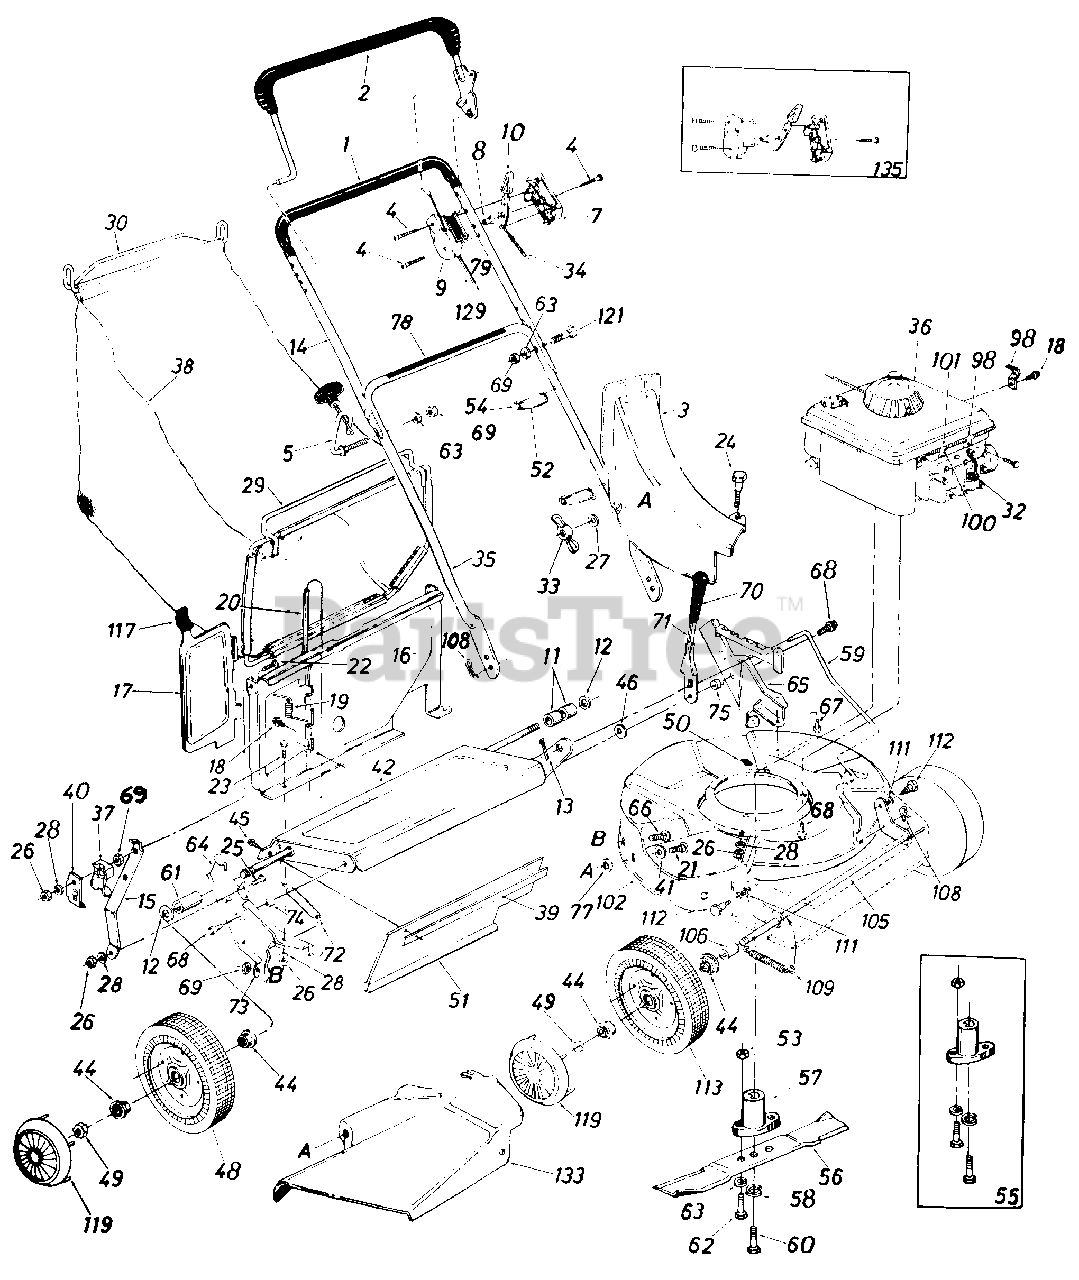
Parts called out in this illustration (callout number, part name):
2	Control Handie Ass'y.-L.H.
3	Top Discharge Chute Ass'y.
4	Truss Mach. Scr. #12 x 1.50" Lg.
5	Rope Guide Bolt
7	Control Panel Half
8	Control Disc Pin
9	Clutch Panel Half
10	Throttle Control Lever
11	Spacer .526" I.D. x .690" O.D. x . 640 I Lg .
12	Fl-Wash. 510 I.D. x .75"
13	Cotter Pin 3/32" Dia. x .75"*
14	Upper Handle-Chrome
15	Panel Support Brkt.
16	Top Catcher Panel
17	Top Door
18	Hex B-Tap Scr. #10 x .38"
19	Torsion Spring
20	Pivot Pin
21	Carriage Bolt 1/4-20 x .62"
22	Truss Mach. Scr. 1/4-20 x 1.0" Lg.
23	Hex Bolt 1/4-20 x .50" Lg.
24	Shoulder Bolt .312 Dia. x .18 Lg. Special
25	Hex Bolt 1/4-20 x .62" Lg.
26	Hex Nut 1/4-20 Thd.
27	Fl-Wash. .280" I.D. x .620"
28	L-Wash. 1/4" I.D.
29	Front Grass Catcher Frame
30	Grass Catcher Handle
32	Spark Plug Insulator
33	Wing Nut
34	Throttle Control Wire 58"
35	Lower Handle-Chrome
36	Engine
37	Rope Guide Half
38	21" Top Discharge Grass Bag
39	Retaining Strip
40	Rope Retainer Spring Clip
41	Fl-Wash. .344" I.D. x .62"
42	Rear Axle Ass'y.
44	Flange Ball Bearing 1/2" I.D.
45	Hex AB-Tap Scr. 1/4 x .62"
46	Fl-Wash. .38" I.D. x 1.0"
48	Rear Wheel Ass'y.-Comp. 8 x 1 .75
49	Hex L-Nut 1/2-20 Thd.
51	Rear Flap 3.75" x 17.30" Lg.
52	Cable Tie
53	Hex Nut 5/16-24 Thd.
54	Cable Anchor
55	Blade Adapter Kit
56	21" Blade
57	Blade Adapter
58	L-Wash. 3/8" I.D.-H.D.
59	Height Adj. Rod. 19.42" Lg.
60	Hex Bolt 3/8-24 x .25" Lg. (Grade 5)
61	Spacer .513" I.D. x .703" O.D.
62	Hex Bolt 5/16-24 x 1.00" Lg. (Grade 5)
63	L-Wash. 5/16" I.D.*
64	R.H. Handle Wheel Brkt. Ass'y.
65	L.H. Handle Wheel Brkt. Ass'y.
66	Carriage Bolt 5/16-18 x .62"
67	Hex Wash. Hd. B-Tap Scr. 5/16-1 8
68	Hex Wash. Hd. TT-Tap Scr. 3/8-16
69	Hex Nut 5/16-18 Thd.*
71	Height Adj. Lever
72	Extension Spring .50" O.D. x 3.80" Lg.
73	Bell-Wash. .344" I.D. x .88" O.D.
74	Spacer .385" I.D. x .502" O.D. x .270" Lg.
75	Shld. Spacer .500" Dia. x .100
77	Bolt Retainer 1/4 x .50" O.D.
78	Instruction Label
79	Control Label
98	Casing Clamp
100	Hex B-Tap Scr. #10 x .62"
101	Casing Clamp
102	21"-Deck Ass'y.
105	Front Axle Ass'y.
106	Sleeve .526" I.D. x .690" O.D. x .880" Lg.
108	Intern. Cotter Pin 5/16" Dia.
109	Extension Spring .50" O.D. x 3.20" Lg.
111	Intern. L-Wash. 3/8 I.D.
112	Shld. Bolt .623" Dia. x .425
113	Front-Wheel Ass'y. Comp. 7 x 1.50
117	Door Grip
119	Hub Cap-Plastic-Black
121	Curved Carr. Bolt 5/16-18 x 1.38" Lg.
129	Control Cable-43" Lg.
133	Side Chute Deflector Ass'y.
135	Kit-Control Housing Comp.
